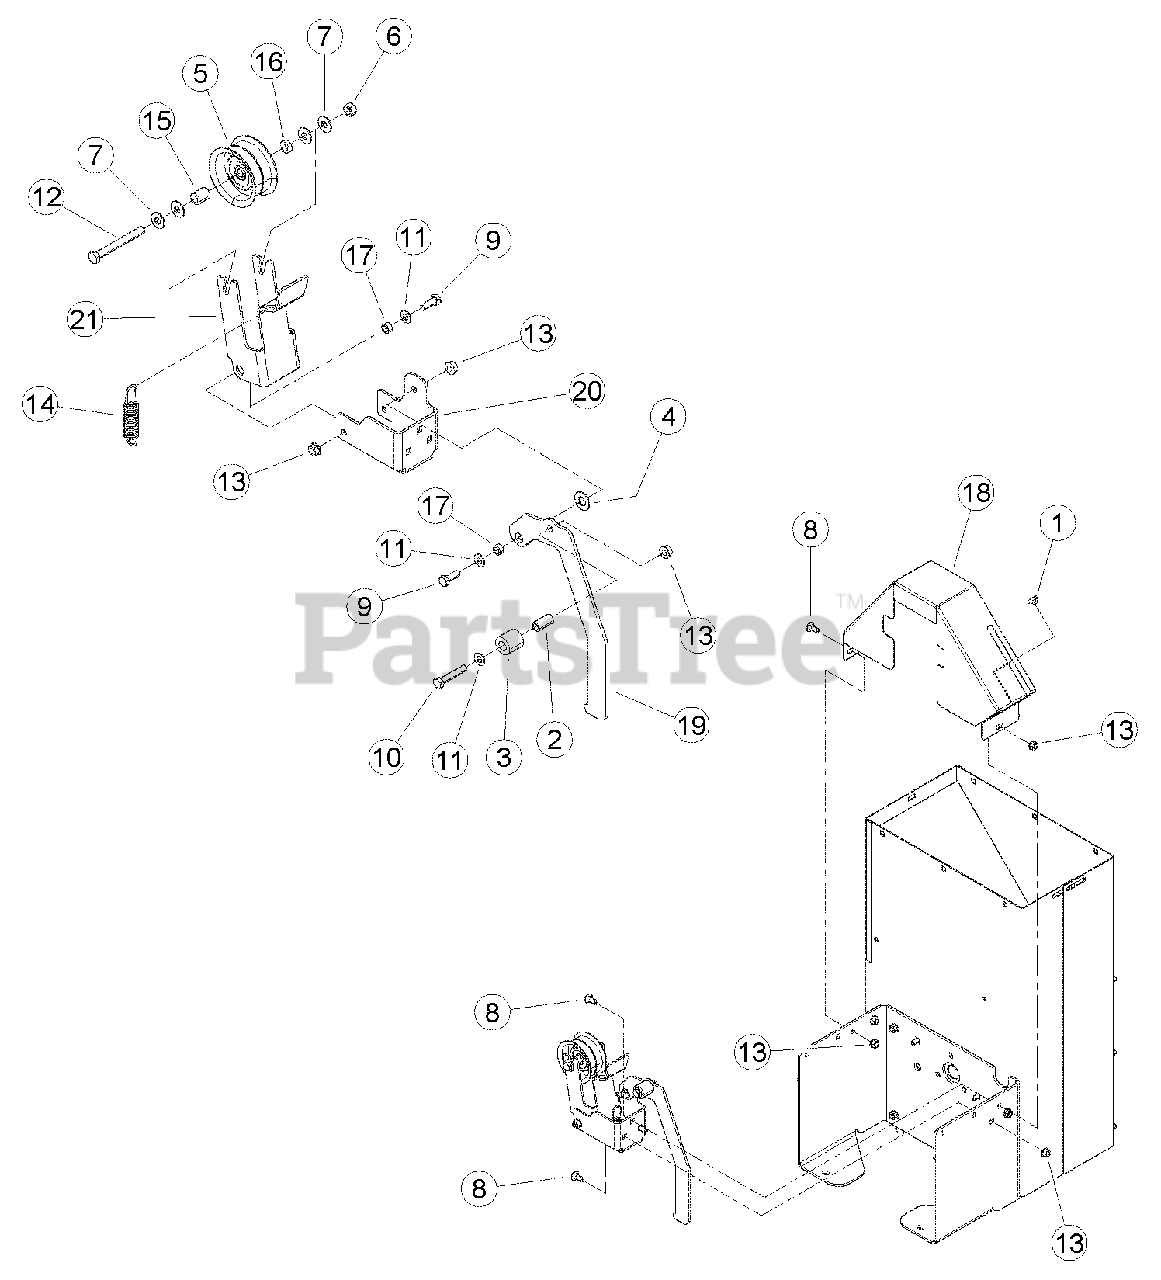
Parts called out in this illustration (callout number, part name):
1	BUMPER, RUBBER
2	SPACER, 0.5 X 1.00
3	ROLLER, 0.5 X 1.00 X 1.00 NYLON
4	NYLON WASHER, 1/2 INCH
5	IDLER, 2.75 X 1.25
6	NUT, 3/8 CENTERLOCK ZP
7	WASHER, 5/16 FLAT ZP
8	BOLT, 5/16 X 3/4 CRG GR5 NC ZP
9	BOLT, 5/16 X 7/8 HEX HD NC GR5 ZP
10	BOLT, 5/16-18 X 1-3/4 HEX HD GR5 ZP
11	WASHER, 5/16 SAE FLAT ZP
12	BOLT, 3/8 X 3-1/4 HEX HD GR5 ZP
13	NUT, 5/16 FLANGE TOPLOCK
14	SPRING, 3/4"OD EXTENSION
15	SPACER, 3/4" LONG IDLER TUBE
16	SPACER, IDLER PIVOT
17	SPACER, .50 X .25
18	SHIELD, UPPER
19	HANDLE, ENGAGEMENT
20	MOUNT, IDLER BRACKET
21	BRACKET, IDLER 3 IN CHIPPER
